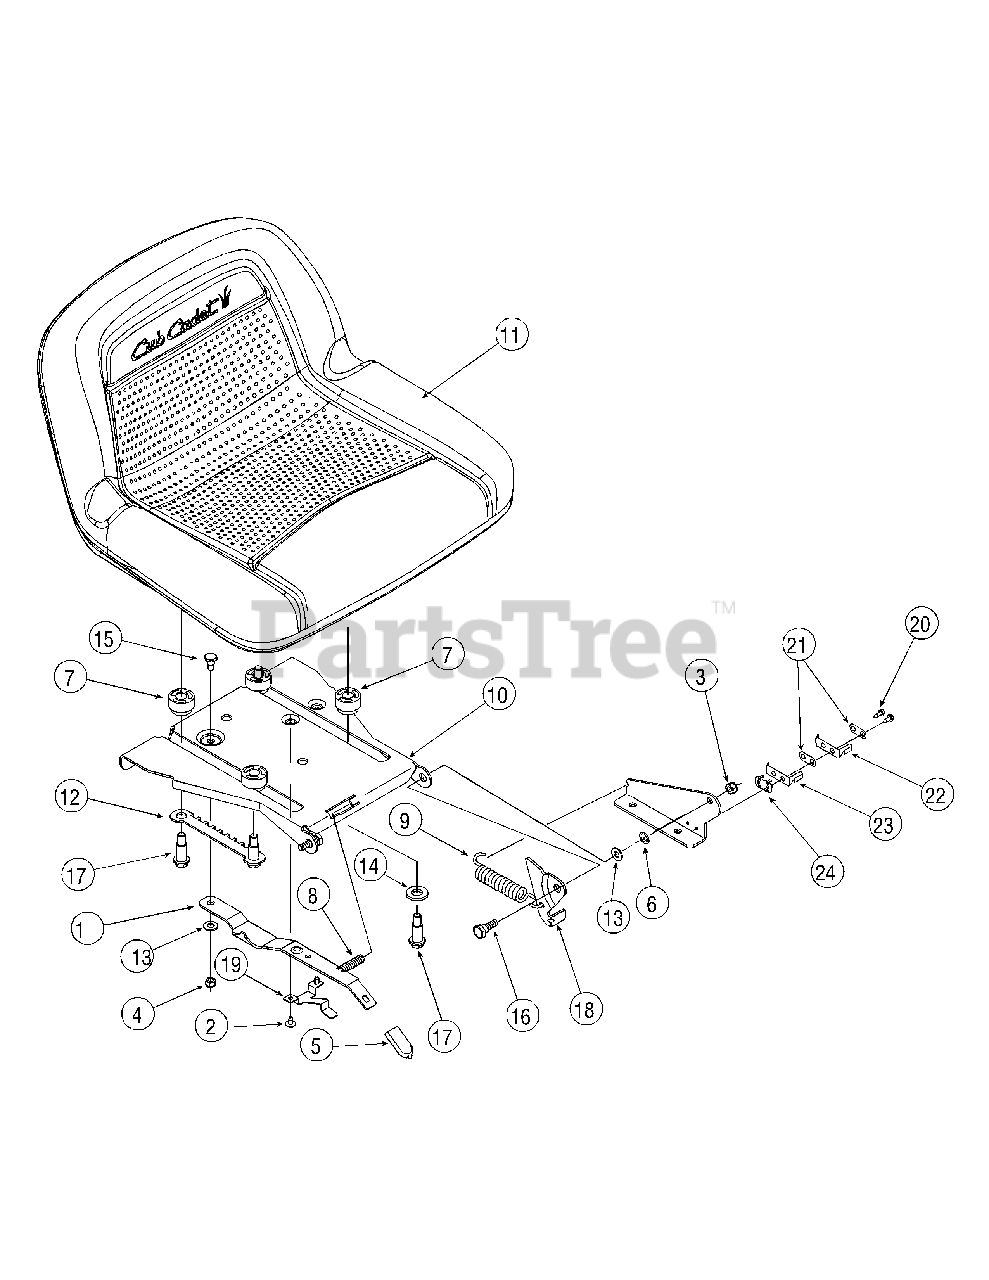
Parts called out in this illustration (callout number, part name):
2	Screw, #10-16, 0.375
3	Nut, Nylon Lock, 5/16-18, Gr5
4	Nut, Nylon Lock, 1/4-20 GrF
5	Grip, Seat, Adjustment (Yellow)
6	Nut, Speed, .3125 ID
7	Spacer, Seat, Adjustment
8	Spring, Compression .41 x 1.50
9	Spring, Extension, .80 Dia x 4.6
11	Seat, Cub Cadet, High Back, Bead
11	Seat, Cub Cadet, Medium Back, Bead
11	Seat, High Back, Black
12	Selector, Seat, Adjustment
13	Washer, Flat, .344 x ..620 x .033
14	Washer, Flat, .531 x 1.062 x .134
15	Screw, Shlder, .340 x .285, 1/4-20
16	Shoulder, Screw .437 x .286 Lg
17	Screw, Shoulder, .50 x.925, 3/8-16
18	LH Bracket, Seat Lift
19	Stop, Seat, Adjustment
20	Screw, #8-18 x .50
21	Plate, Insulator
22	Spring Switch, Outer
23	Spring Switch, Inner
24	Plate, Insulator Boss
